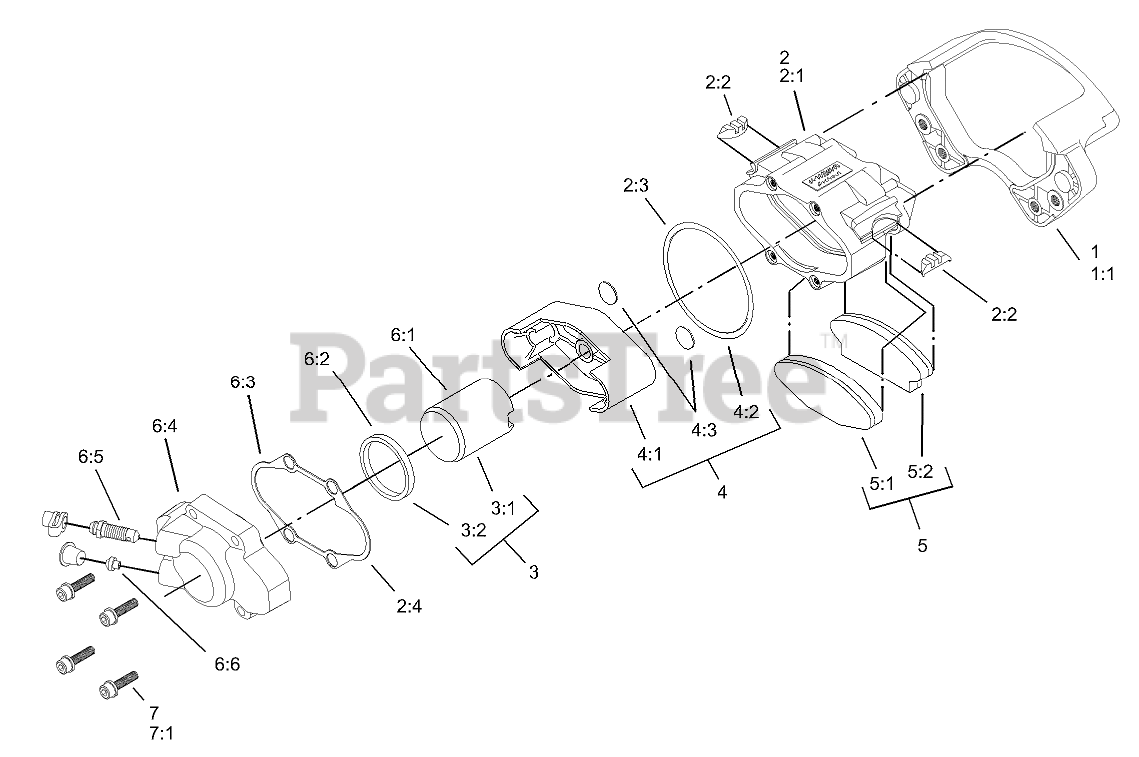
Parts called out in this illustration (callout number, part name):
1	BRACKET KIT
1:1	Bracket
2	HOUSING KIT
2:1	Housing
2:2	Spring-Rubber
2:3	Seal-Dust
2:4	Gasket
3	PISTON & SEAL KIT
3:1	Piston-Round
3:2	Seal-Square
4	PISTON & O-RING KIT
4:1	Piston-Oval
4:2	Seal-Dust
4:3	Plug-Piston
5	PAD KIT
5:1	Pad/Holder ASM
5:2	Pad/Holder ASM
6	RH PISTON & COVER ASM KIT
6:1	Piston-Round
6:2	Seal-Square
6:3	Gasket
6:4	Cover
6:5	Screw-Bleeder
6:6	Insert-Seat
7	BOLT KIT
7:1	Screw-Cover
